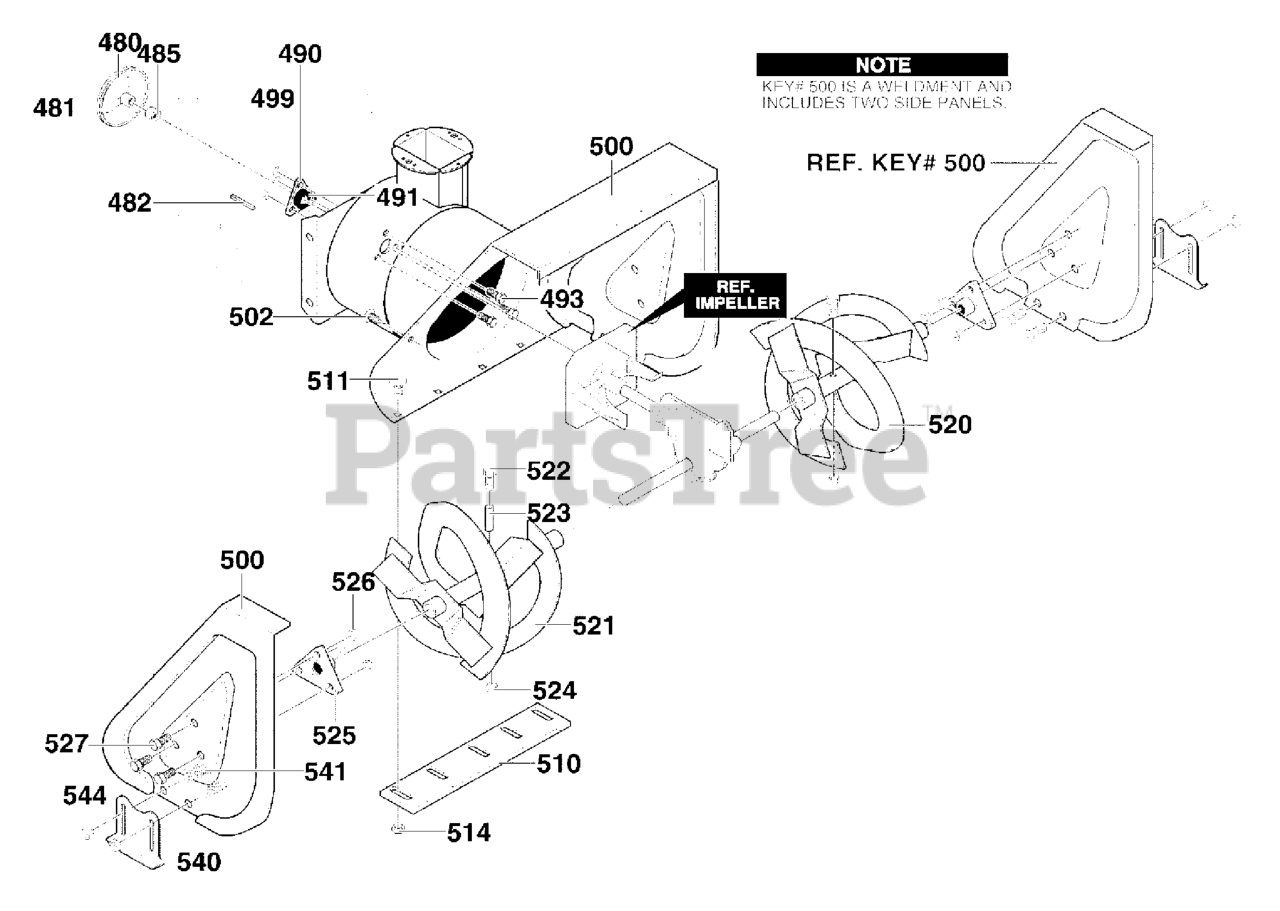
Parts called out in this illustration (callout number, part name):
480	PULLEY, 4L 6.12X .67
481	SCREW, 5/16-18 x 0.63
482	KEY, SQUARE
485	SPACER, SLEEVE .676X1.00X.53
490	RETAINER, BALL BRNG
491	BEARING, BALL
493	SCREW, 5/16-18 x 0.75
499	NUT, 5/16-18 HEXWDFLLK
500	HOUSING, ASSY
502	FASTENER, RATCHET
510	BLADE, SCRAPER 24"
511	BOLT, 1/4-20X.75
514	NUT, 1/4-20
520	AUGER, ASSY, LH
521	AUGER, ASSY, RH
522	SCREW, 1/4-20X1.75
523	SPACER, SLEEVE
524	NUT, 1/4-20 REGHEXCTRLK
525	BEARING,FLANGE
526	NUT, 5/16-18
527	SCREW, 5/16-18 x 0.75
540	SKID, HEIGHT ADJUST
541	BOLT, 5/16-18 X .75
544	NUT, 5/16-18 REGHEX
